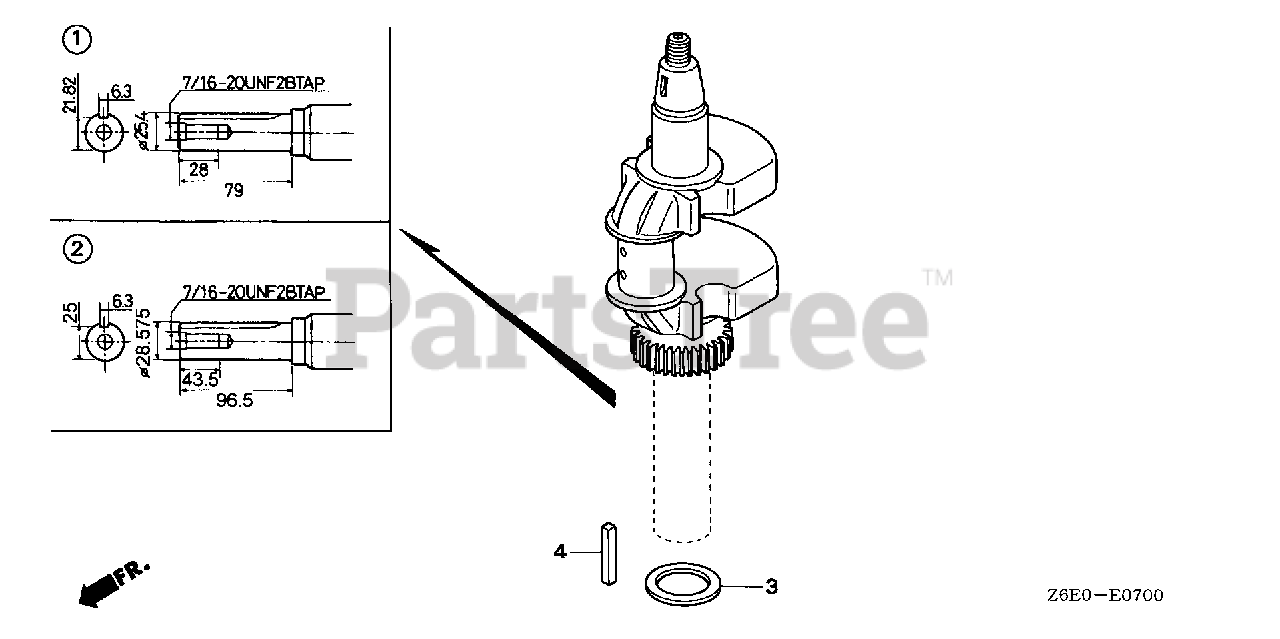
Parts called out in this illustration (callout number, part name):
1	CRANKSHAFT
3	WASHER, CRANKSHAFT THRUST (38.5X54.0X1.0)
4	KEY (6.3X6.3X43)
